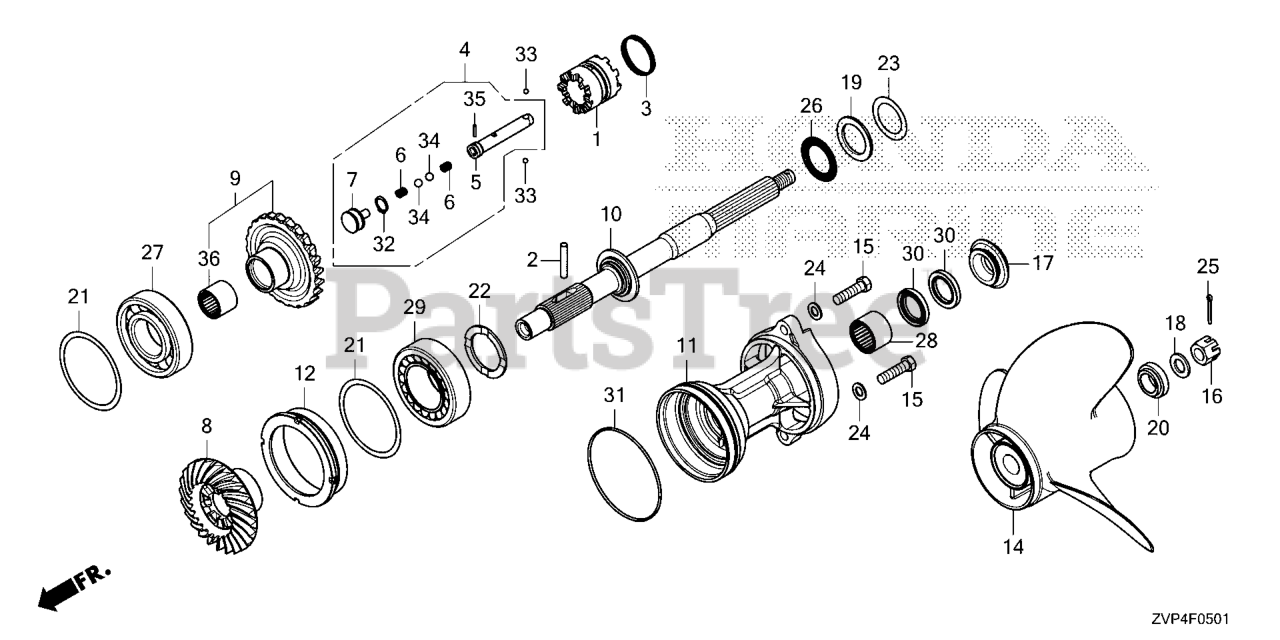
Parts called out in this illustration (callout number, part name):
1	SHIFTER, CLUTCH
2	PIN, SHIFTER (8X50)
3	RING, CROSS PIN
4	SLIDER COMP, SHIFT
5	SLIDER, SHIFT
6	SPRING, SHIFT
7	PLATE, SHIFT
8	GEAR, BEVEL F C/R
10	SHAFT, PROPELLER
11	HOLDER *NH565*
11	HOLDER *NHB14M*
12	HOLDER A, BRG C/R
14	PROP COMP (3-BLADE)
15	BOLT, HEX. (12X45)
16	NUT, CASTLE (18MM)
17	WASHER, PROP THRUST
18	WASHER, PLAIN (18.5MM)
19	WASHER, THRUST BEARING
20	WASHER, PROP
21	SHIM A, BEVEL F
21	SHIM B, BEVEL F
21	SHIM C, BEVEL F
21	SHIM D, BEVEL F
22	WASHER (52X71X4)
23	SHIM A, THRUST (0.10)
23	SHIM B, THRUST (0.15)
23	SHIM C, THRUST (0.30)
23	SHIM D, THRUST (0.50)
24	WASHER, PLAIN (12MM)
25	PIN, SPLIT (4.0)
26	BEARING, THRUST (F)
27	BRG (50X110X27)
28	BRG (35X45X30)
29	BRG (60X110X38)
30	SEAL (35X50X7)
31	O-RING (121X3.1)
32	CIRCLIP (OUTER) (18MM)
33	BALL, STEEL (#7) (7/32)
34	BALL, STEEL (#12) (3/8)
35	ROLLER (3X16.8)
36	BEARING, NEEDLE (28X39X30)
